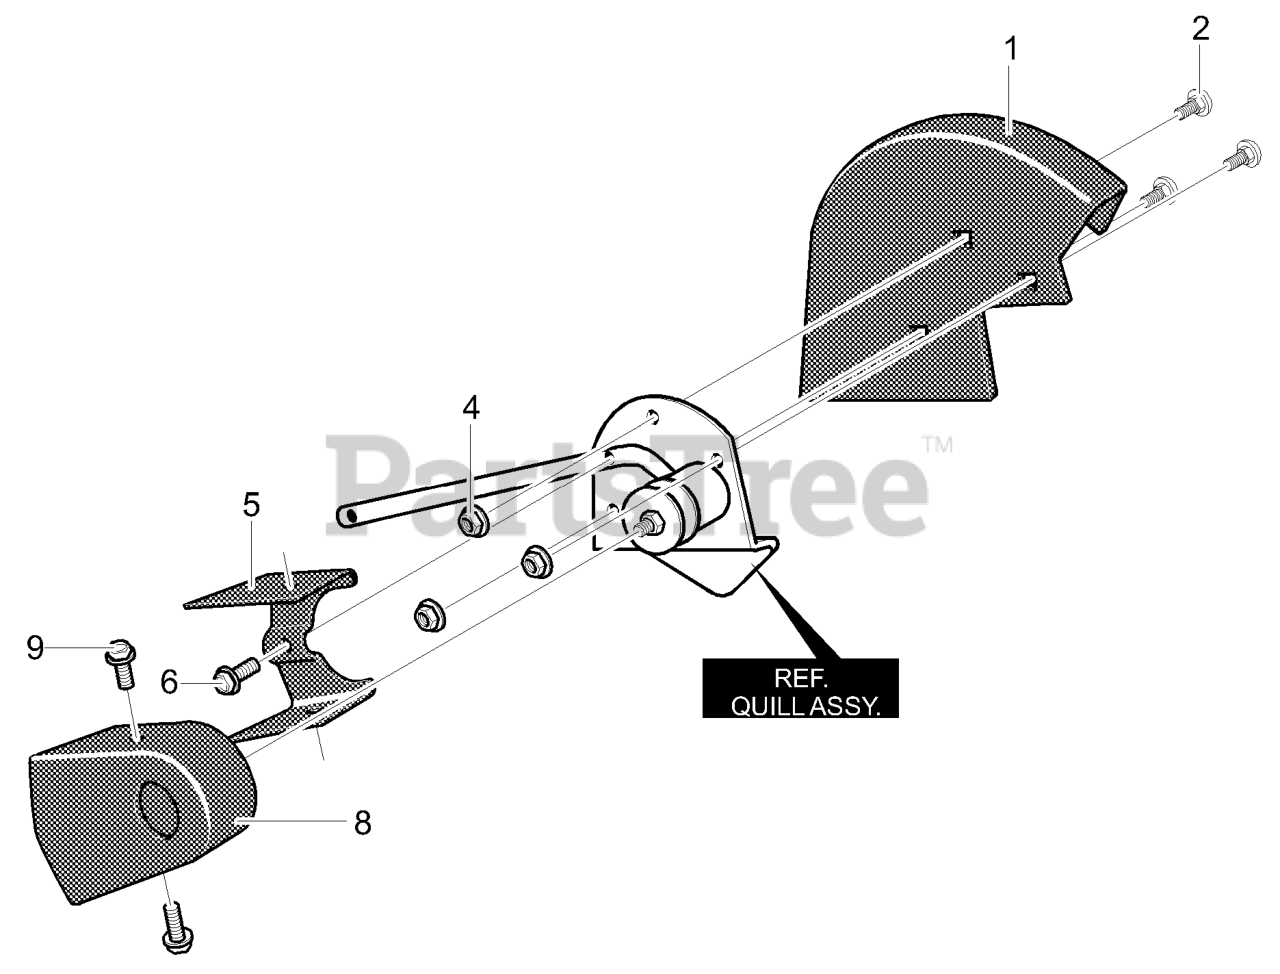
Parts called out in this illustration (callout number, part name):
1	Blade Guard
2	Bolt, 5/16-18x.63 Carr.
4	Nut, 5/16-18 Wdfllk Whiz
5	Guide, Belt Front
6	Screw, 1/4-20x.50
8	Cover, Quill Pulley
9	Screw, 10-16x.50
